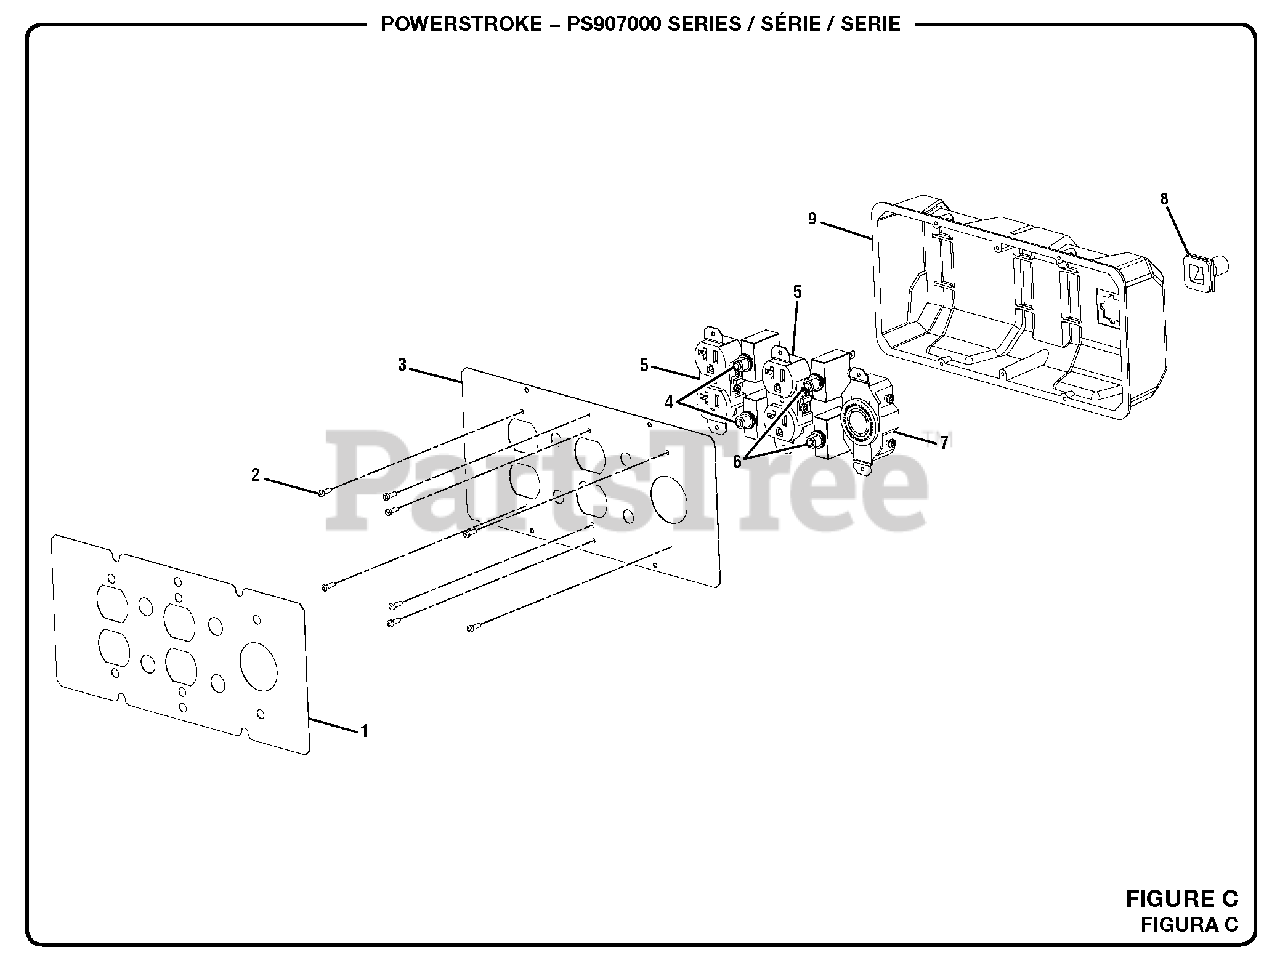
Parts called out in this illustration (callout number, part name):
1	Label (Power Outlet)
2	Screw (6-20 x 3/8 in.)
3	Front Panel
4	Circuit Breaker (20 Amp, 125 Volt)
5	120 Volt Duplex Receptacle (GFCI)
6	Circuit Breaker (30 Amp)
7	Twist Lock Receptacle (120/240 Volt, 30 Amp, L14-30R)
8	Rubber Boot
9	Control Box (Back Panel)
